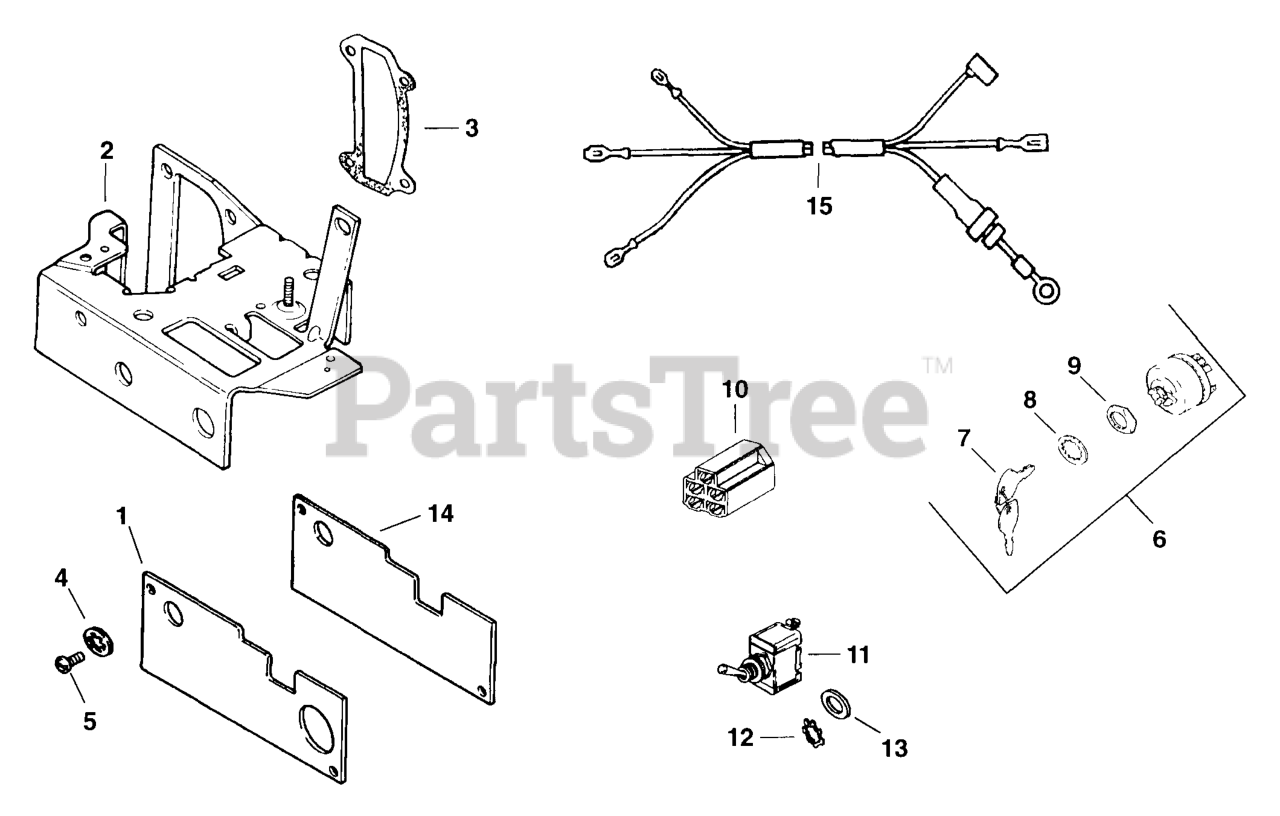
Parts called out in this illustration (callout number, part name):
1	PANEL - DISCONTINUED
5	SCREW - DISCONTINUED
6	SWITCH ASSY, KEY (KM)-USE 25 099 32-S
7	KEY (KM)
8	WASHER, INTERNAL TOOTH
9	NUT, KEY SWITCH
10	CONNECTOR
15	HARNESS
